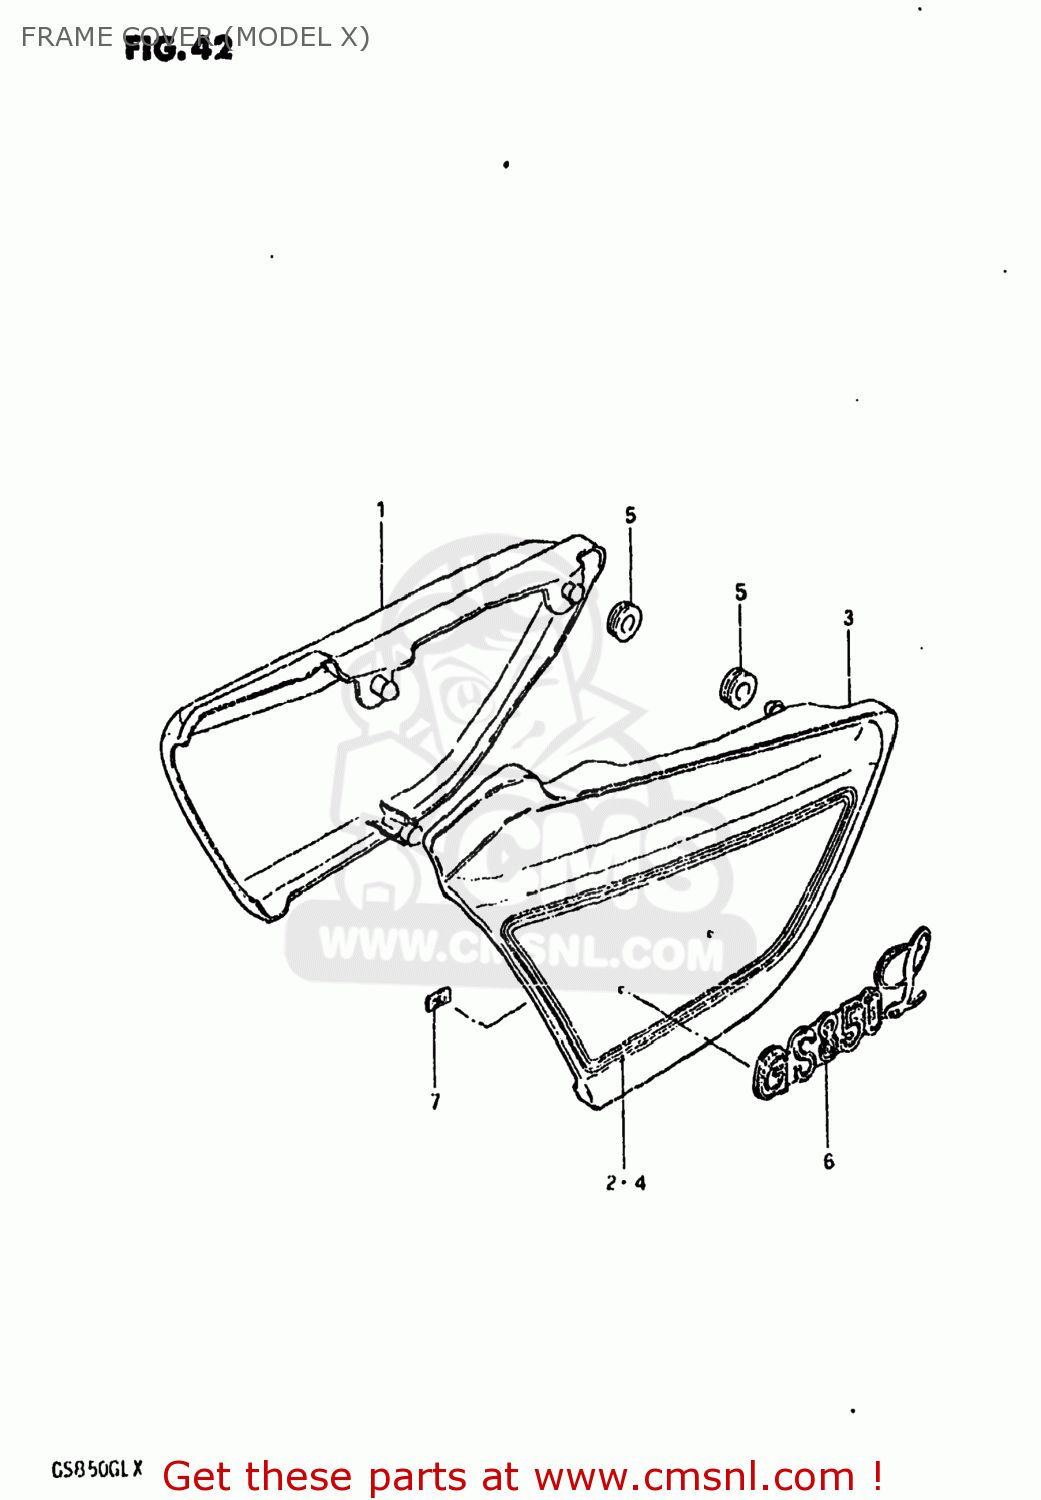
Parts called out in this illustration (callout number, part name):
1	COVER ASSEMBLY,FRAME,RIGHT
2	TAPE SET,FRAME COVER,RIGHT
3	COVER ASSEMBLY,FRAME,LEFT
4	TAPE SET,FRAME COVER
5	CUSHION
6	EMBLEM
7	NUT
